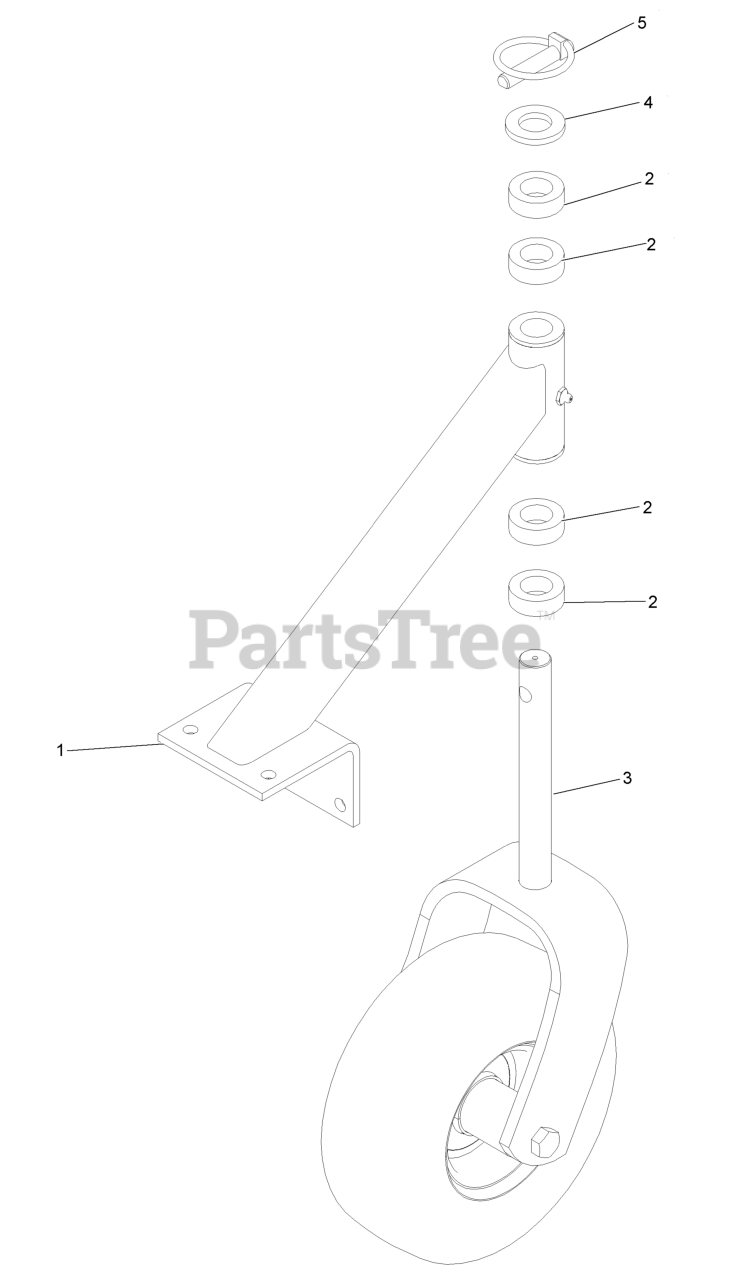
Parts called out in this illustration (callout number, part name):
1	Caster Whl Support W/Bearings, Weighted
2	Spacer-Caster
3	Caster Wheel Assembly
